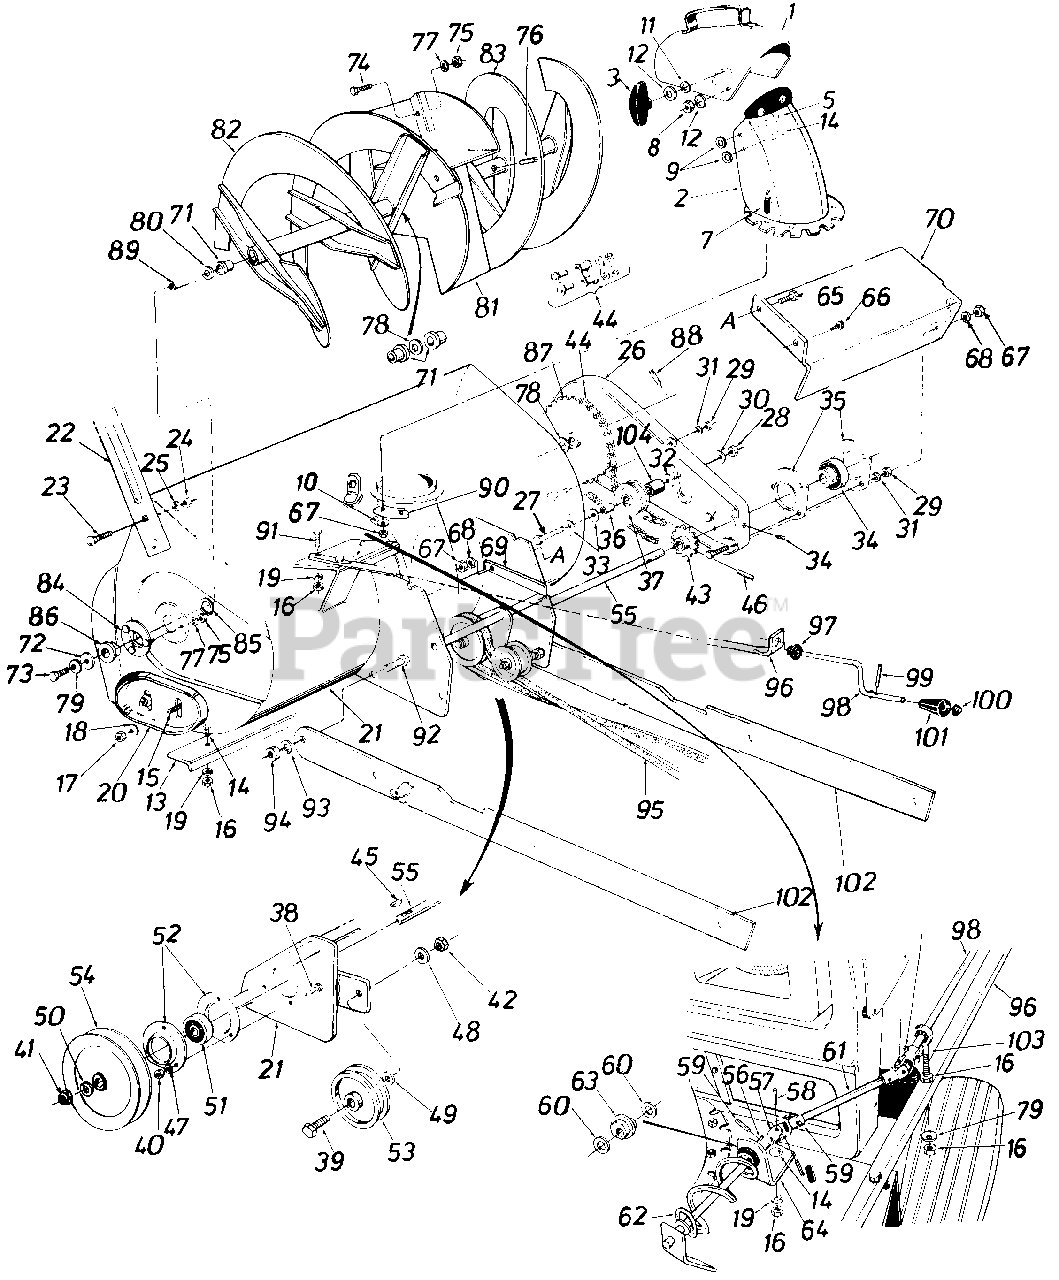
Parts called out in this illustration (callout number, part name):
1	Top Chute Ass'y
2	Chute Ass'y w/Guard
3	Knob Handle Ass'y.
5	Carriage Bolt 5/16-18x 1.0" Lg.
7	Truss Mach Scr 1/4-20 x 75" Lg.
8	Hex Cent. L-Nut 5/16-18 Thd.
9	Fl.-Wash. .531" I.D. x 1.25" O.D
10	Bell. Wash 1/4" I.D.
11	Fl.-Wash .344" 1 D x 1.125" O.D.
12	Bell Wash . 345" 1 D x .88" O.D.
14	Carriage Bolt 5/16-18 x .62" Lg.
15	Carriage Bolt 3/8-16 x .62" Lg.
16	Hex Nut 5/16-18 Thd.'
17	Hex Jam Nut 3/8-16 Thd
18	Bell. Wash. .400" I.D. x .88" O.D.
19	L.-Wash. 5/16" I.D.
20	Slide Shoe
21	Spiral Hsg. Ass'y.-36"
22	Guide Blade
23	Carriage Bolt 5/16-18 x .62" Lg.
24	Hex Nut 5/16-18 Thd.
25	L.-Wash. 5/16" I.D.
26	Chain Guard Ass'y.
27	Hex Bolt 3/8-16 x 2.00 Lg.
28	Hex Inst.-Nut 3/8-16 Thd.
29	Hex Nut 5/16-18 Thd.
30	Bell.-Wash. .400" I.D. x .88 O.D.
31	L.-Wash. 5/16" I.D.
32	Fl.-Wash. .406" I.D. x 1.25" O.D.
33	Fl-Wash. .385" I.D. x .87" O.D.
34	Ball Brg. .75" I.D.
35	Flangette
36	Spacer .375" I.D. x .60" O.D.
37	Fl.-ldler w/Flanges 1.875 0 O.D. Plastic
38	Hex Sems Bolt 5/18 x .75" Lg.
39	Hex Bolt 3/8-16 x 1.75" 4.
40	Hex Nut 5/16-18 Thd.
41	Hex Jam Nut 3/4-10 Thd.
42	Hex Jam Nut 3/8-16 Thd.
43	Sprocket Ass'y.-14 Teeth
44	#420 Chain x 1/2" Pitch- 78 Links
45	#61 Hi-Pro-Key 3/16 x 5/8" Dia.
46	Spring Pin Spir. 5/16" Dia. x 1 75" Lg.
47	L.-Wash. 5/16" I.D.
48	L.-Wash. 3/8" I.D.
49	Fl.-Wash. .406" I.D. x 1.25" O.D.
50	Spring L.-Wash. 3/4' 1 D.
51	Self-Aligning Brg.
52	Flangette
53	Idler Pulley
54	5 8 V Pulley .75" I D x 6 0 0 O D
55	Drive Shaft Ass'y
56	Joint Brkt Ass
58	Oval Head Rivet
59	Spirol Pin 1 8" Dia x .812" Lg .
60	Fl Wash .385" 1 D x .62 " O D
61	Chute Crank Ext Rod 3 8' Dia x 6.0 Lg
62	Chute Crank Ass'y R H 0 6-1/4" Lg.
63	Plastic Bushing .380" 1 D
64	Chute Crank Brkt
65	Hex Bolt 1/4-20 x .62" Lg '
66	Hex Wash S-Tap Scr 1/4-20 x .50" Lg.
67	Hex Nut 1/4-20 Thd
68	L.Wash. 1/4 I.D
70	Drive Shaft Cover
71	Plastic Bushing
72	Washer .39" I.D. x 1.75" O.D
73	Hex Bolt 5/16-18 x .88" Spec.
74	Carnage Bolt 5/16-18 x 75" Lg. '
75	Hex Nut 5/16-18 Thd.
76	Spring Pin Spiral 5/16" Dia. x 1.75" Lg.
77	L. Wash. 5/16" I.D.
78	Fl Wash. 1.03" I.D. x 1.62" O.D.
79	Bell.-Wash. .345" I.D. x .88 O.D
80	Fl.-Wash. 1.0" I.D x 1 75" O D.
85	Snap Ring for 1.50" Shaft
86	Flange Brg. w/flats 1.00" I.D.
87	Sprocket Hub Ass'y. 40 Teeth
88	Spring Pin Spir 5/16 Dia. x 1 75" Lg.
90	Chute Flange Keeper
91	Hex Bolt 5/16-18 x 1.5" Lg.
92	Hex Bolt 1/2-13 x 1.25" Lg.
93	L-Wash. 1/2" 1 D.
94	Hex Nut 1/2-13 Thd
95	'V"Belt 1/2" "A" x 89.0" Lg.
98	Chute Crank .375" Dia. x 34.5" Lg
99	Roll Pin .12 Dia. x .63"
100	Push Nut 3/8" Rod
101	Knob Black
102	Linkage Arm
103	Eve Bolt 5/16-18 x 3.0" Lg.
104	Idler Spacer .377 I.D. x .624 O.D. x ..840
